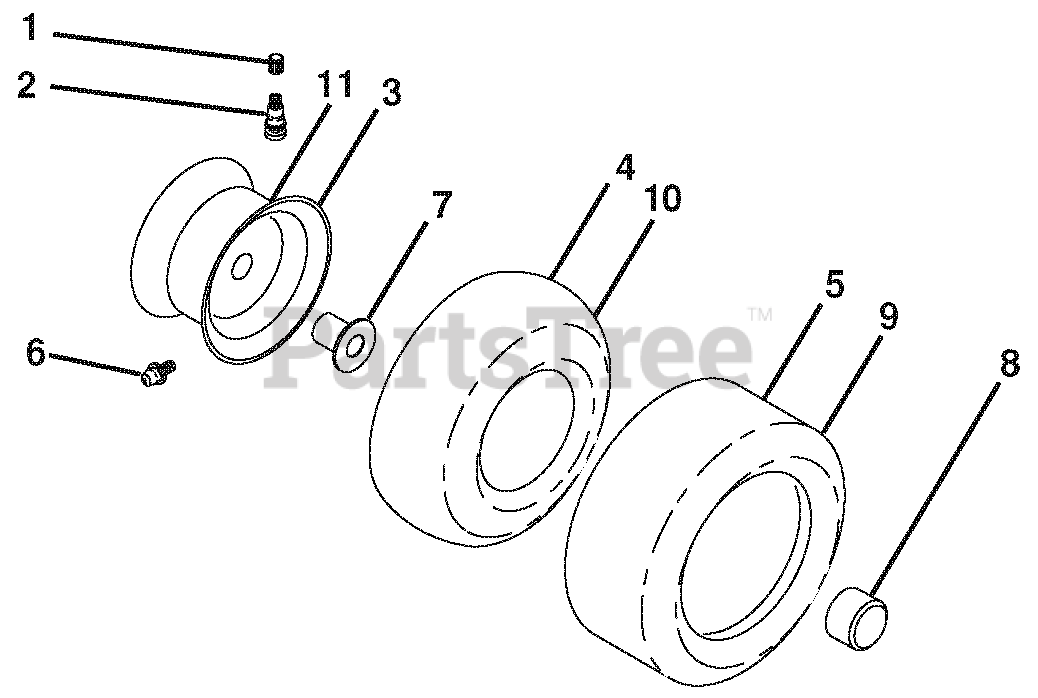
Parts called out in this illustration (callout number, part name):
1	CAP.VALVE.TIRE
2	STEM.VALVE
3	RIM ASSEMBLY 6" FRONT
4	TUBE, FRONT(SERVICE ITEM ONLY)
5	TIRE.F.TS.15 X 6.0 - 6.SERVICE
6	FITTING, GREASE
7	BEARING FLANGE
8	CAP AXLE (FRONT WHEEL ONLY)
9	TIRE.R.TS.20 X 8-8.C.SERVICE
10	TUBE, REAR (SERVICE ITEM ONLY)
11	RIM ASSEMBLY 8" REAR
